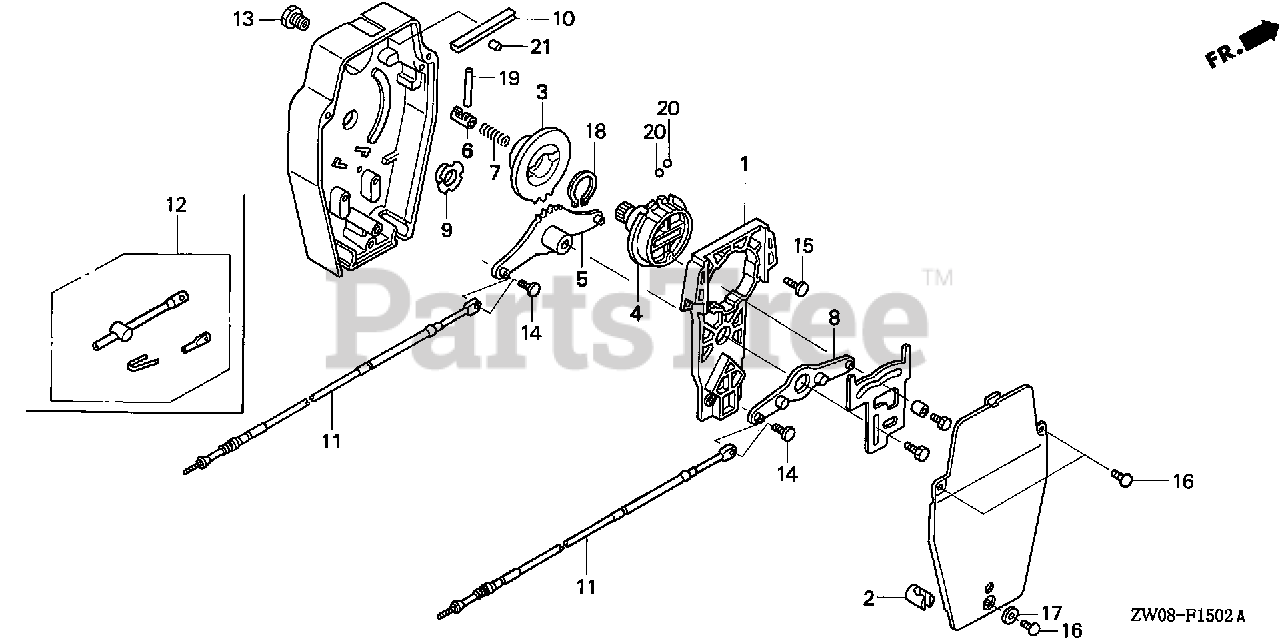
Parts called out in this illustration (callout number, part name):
1	FRAME ASSY., REMOTE CONTROL BOX
2	GROMMET
3	WHEEL, CONTROL
4	SHAFT, HANDLE (N/A: SEE ASSEMBLY) (NOT AVAILABLE)
5	ARM ASSY., SHIFT LINK
6	SHAFT, GEARSHIFT
7	SPRING, GEARSHIFT
8	ARM ASSY., THROTTLE LINK
9	BUSH
10	SPRING
11	CABLE, REMOTE CONTROL (10'') (TELEFLEX)
11	CABLE, REMOTE CONTROL (10') (NOT AVAILABLE)
11	CABLE, REMOTE CONTROL (11') (TELEFLEX)
11	CABLE, REMOTE CONTROL (1 1'') (BRUNSWICK) (NOT AVAILABLE)
11	CABLE, REMOTE CONTROL (12') (TELEFLEX)
11	CABLE, REMOTE CONTROL (1 2'') (BRUNSWICK) (NOT AVAILABLE)
11	CABLE, REMOTE CONTROL (13') (TELEFLEX)
11	CABLE, REMOTE CONTROL (1 3'') (BRUNSWICK) (NOT AVAILABLE)
11	CABLE, REMOTE CONTROL (14') (TELEFLEX)
11	CABLE, REMOTE CONTROL (1 4'') (BRUNSWICK) (NOT AVAILABLE)
11	CABLE, REMOTE CONTROL (15') (TELEFLEX)
11	CABLE, REMOTE CONTROL (1 5'') (BRUNSWICK) (NOT AVAILABLE)
11	CABLE, REMOTE CONTROL (16') (TELEFLEX)
11	CABLE, REMOTE CONTROL (1 6'') (BRUNSWICK) (NOT AVAILABLE)
11	CABLE, REMOTE CONTROL (17') (TELEFLEX)
11	CABLE, REMOTE CONTROL (17'') (TELEFLEX)
11	CABLE, REMOTE CONTROL (1 7'') (BRUNSWICK) (NOT AVAILABLE)
11	CABLE, REMOTE CONTROL (18') (TELEFLEX)
11	CABLE, REMOTE CONTROL (1 8'') (BRUNSWICK) (NOT AVAILABLE)
11	CABLE, REMOTE CONTROL (19') (TELEFLEX)
11	CABLE, REMOTE CONTROL (1 9'') (BRUNSWICK) (NOT AVAILABLE)
11	CABLE, REMOTE CONTROL (20') (TELEFLEX)
11	CABLE, REMOTE CONTROL (2 0') (BRUNSWICK) (NOT AVAILABLE) (ALT. PNO: 24920-ZW1-003AH)
12	ADAPTER, REMOCON CABLE (N/A: USE 24931-ZW1-000)
13	BOLT
14	SCREW (8-32X3/8)
15	SCREW (10-32X5/8)
16	SCREW (10-32X5/8)
17	WASHER Use up to Frame SN 4000953.
18	CIRCLIP (OUTER)
19	PIN, GEARSHIFT
20	BALL, STEEL
21	ROLLER, SHIFT CLICK
